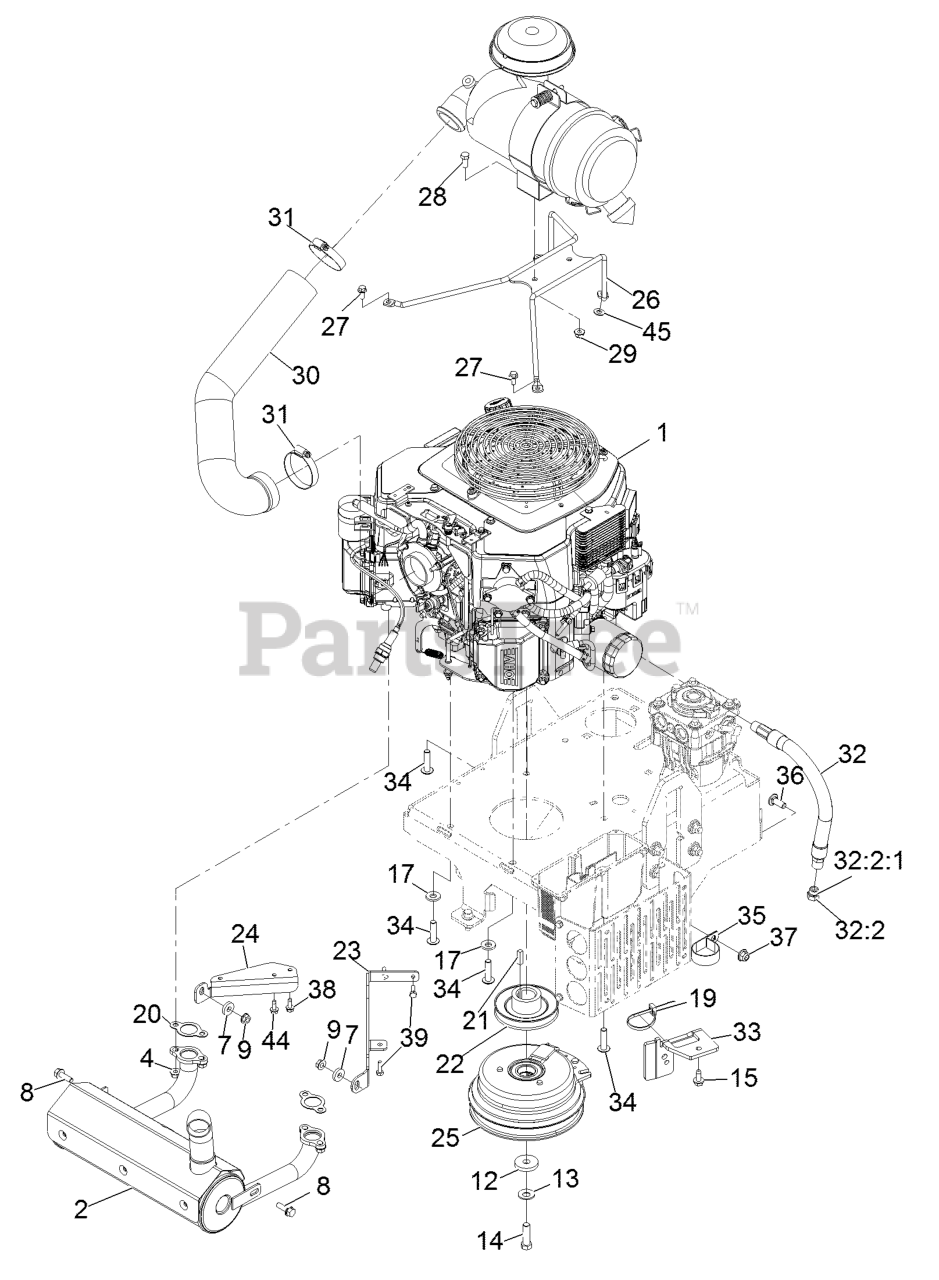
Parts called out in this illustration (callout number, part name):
1	Engine, Kohler
4	NUT-FLANGE
8	SCREW-HHF
12	WASHER
13	WASHER-SPRING
14	SCREW-HH
15	Screw-HWH 5/16-18 X 3/4 Tf
17	WASHER-BELLEVILLE
19	TIE-CABLE
20	GASKET-EXHAUST
23	MOUNT, MUFFLER-LT
24	MOUNT, MUFFLER-RT
25	CLUTCH-200 FT-LB, 1.125 B
26	MOUNT-CLEANER, AIR
27	SCREW-HHF
28	SCREW-HH
29	NUT-HF, NI
30	HOSE-INTAKE, AIR
31	CLAMP-HOSE
32	OIL DRAIN HOSE ASM
32:2	PLUG-HH
32:2:1	O-RING
33	BRACKET-ANCHOR, CLUTCH
34	SCREW-BHTF
35	CLAMP-R
36	SCREW-CARR
37	NUT-HF, NI
38	SCREW-HWHTF
39	SCREW-HH M6-1 X 20Mm W/Patch
44	SCREW-HWHTF
45	WASHER-PLAIN
